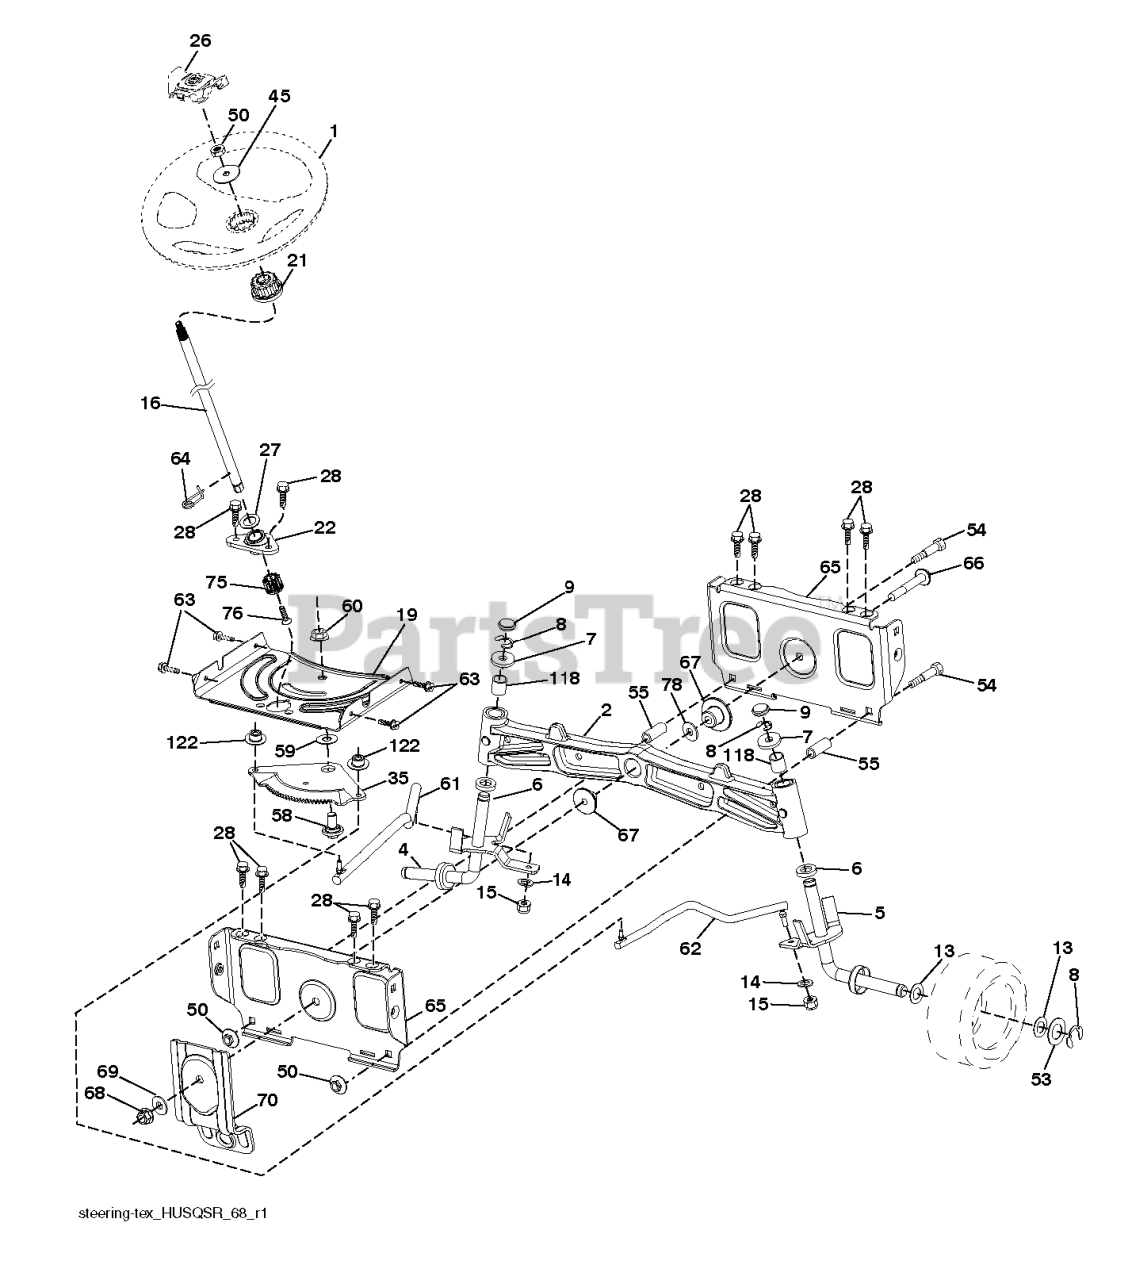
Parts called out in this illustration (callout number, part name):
1	WHEEL.STEER.HUSQ.SR.498.OVMLD
2	AXLE.SVC.ASM CAST IRON.TEX
4	SPINDLE.ASM.LH
5	SPINDLE.ASM.RH
6	THRUST WASHER
9	CAP.SPINDLE.BLACK
14	SLW 3/8 STD
15	NUT CROWNLOCK 3/8-24
16	SHAFT.STEER.2HIGH.SPLND.PLATED
19	PLATE.STEER.DDL.NLT/NG
21	ADAPTER.WHEEL.STEER.SPLND.ALUM
22	BEARING.SHAFT.STEER.LOWER.625
26	INSERT.CAP.WHL.STRG.HUSQ.PREM
27	WASHER LT
28	SCREW, 3/8-16X3/4
35	GEAR.SECTOR.PLATE.DDL.
45	WASHER.3/8ID.2-3/8OD.12GA.PLTD
50	NUT LOCK FLG 3/8-16 UNC
53	WASHER.HARDENED
55	SPACER.BRACE.AXLE
58	BOLT.SHOULDER.SECTOR.P
59	WASHER.THURST.SECTOR.S
60	NUT FLANGE LOCK 5/8-11
61	LINK.ASM.DRAG.ADJUST.LH.PLATED
62	LINK.ASM.DRAG.ADJUST.RH.PLATED
63	SCREW
64	RETAINER.CLIP.SPRING.S
65	BRACE.AXLE.FRONT.NLT/N
66	BOLT HEX FGHD 7/16-14 X 3 SERR
67	BUSHING.PM.FRONT AXLE
68	NUT.LOCK.FLANGE.7/16
69	WASHER.1.5X.505X.118
70	BRACKET.FRT.DECK.SUSP.RR.MT431
75	PINION.ZINC PLATED
76	SCREW HEAD SOCKET LRVB
78	THRUST WASHER
118	BUSHING, AXLE CAST
122	CAP.GEAR.SECTOR.TEX
